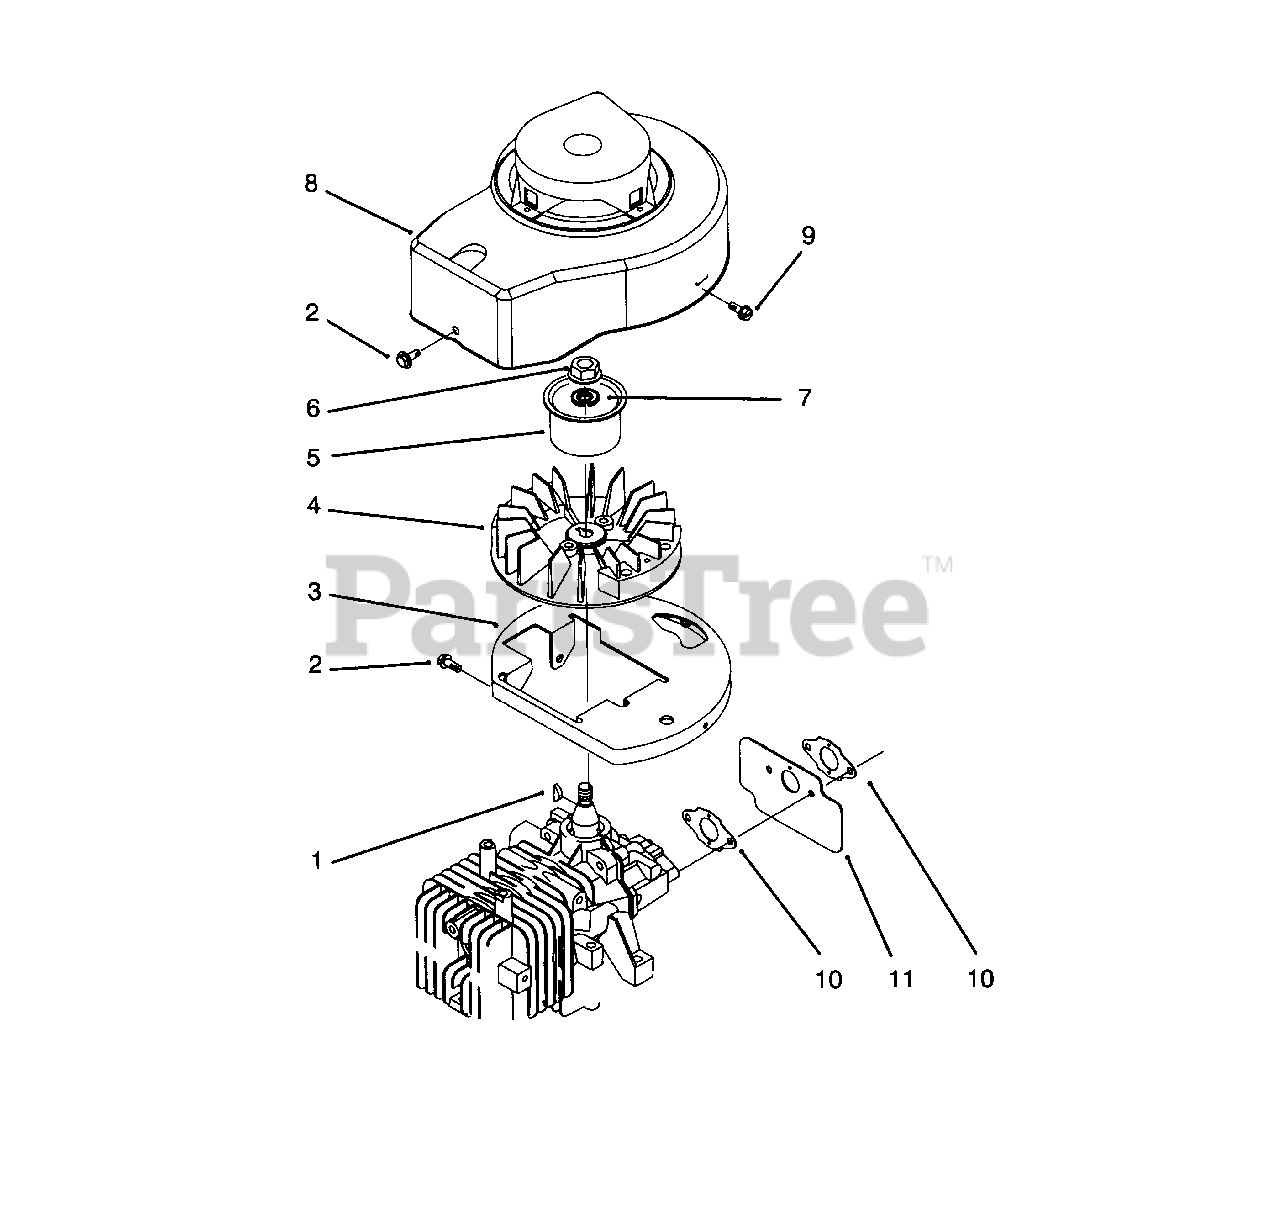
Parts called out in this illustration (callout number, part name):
1	Key-Crankshaft
2	Screw
3	Base-Shroud
4	Flywheel Assembly
5	Hub-Starter
6	Nut-Hex. Flange
7	Washer-Lock
8	Shroud Assembly
10	Gasket-Carburetor
11	Shield-Carburetor
